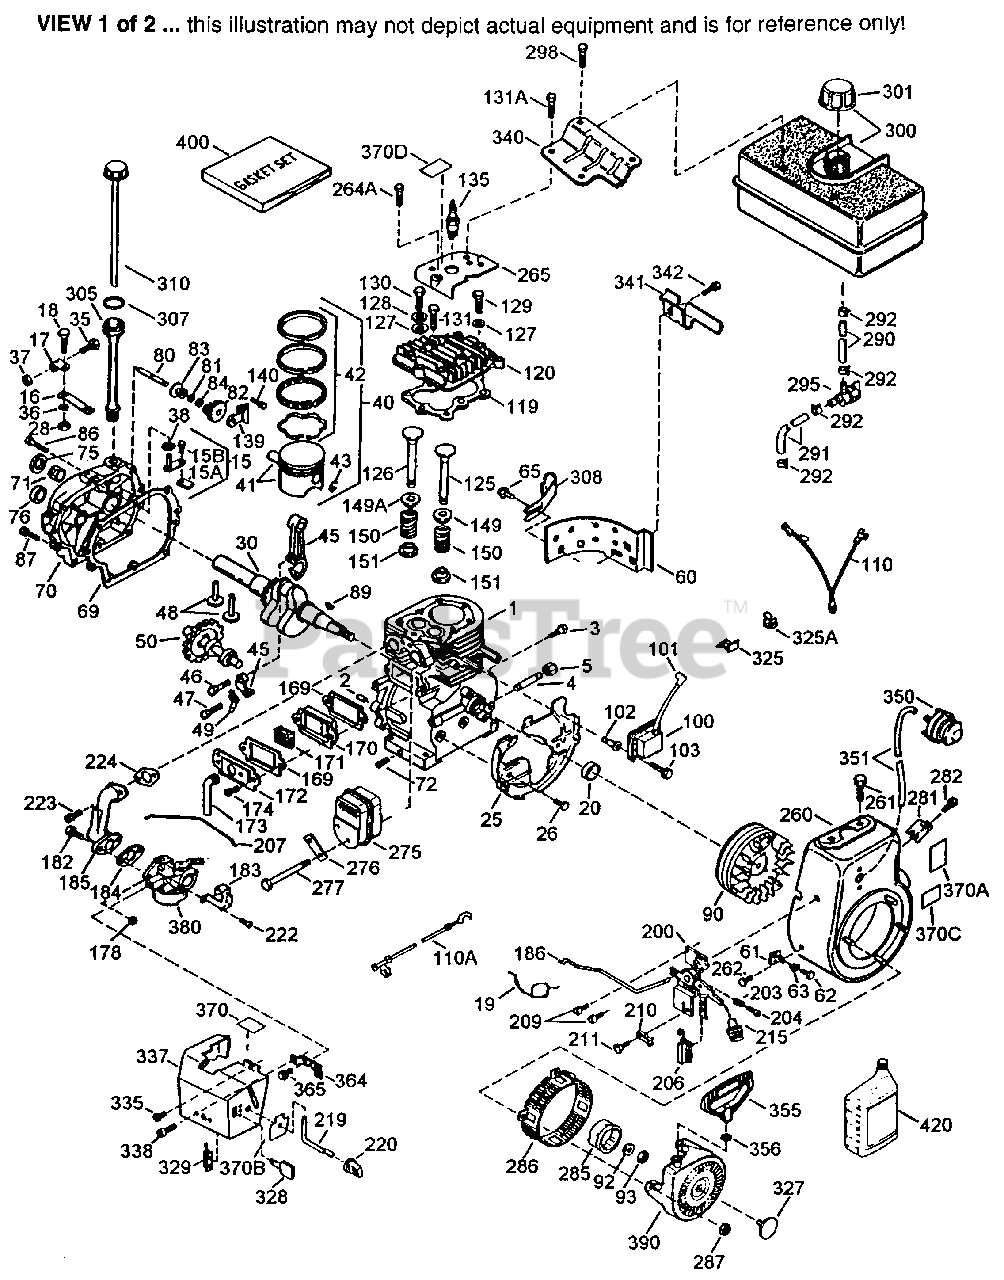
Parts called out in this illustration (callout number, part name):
1	"Cylinder Ass'y. (Incl. 2, 20, 72 & 72 A)(3-1/8" Bore)
2	Dowel Pin
3	Screw, 1/4-20 x 1/2"
4	Oil Drain Extension Purchase Locally
5	Extension Cap
15	Governor Rod (Incl. 15A & 15B)
15A	Governor Yoke
15B	Screw, 6-40 x 5/16"
16	Governor Lever
17	Governor Lever Clamp
18	Screw, 8-32 x 5/16"
19	Speed Control Spring
20	Oil Seal
25	Blower Housing Baffle
26	Screw, 1/4-20 x 5/8"
28	Lock Nut, 8-32
30	Crankshaft
35	Screw, 10-32 x 3/4"
36	Lock Washer #8
37	Lock Nut, 10-32
38	Retaining Ring
40	Piston, Pin & Ring Set (Std.)
40	Piston, Pin & Ring Set (.010" OS)
40	Piston, Pin & Ring Set (.020" OS)
41	Piston & Pin Ass'y. (Std.) (Incl. 43)
41	Piston & Pin Ass'y. (.010" OS) Incl. 43
41	Piston & Pin Ass'y. (.020" OS) Incl. 43
42	Ring Set (Std.)
42	Ring Set (.010" OS)
42	Ring Set (.020" OS)
43	Piston Pin Retaining Ring
45	Connecting Rod Ass'y. (Incl.46,47,49)
46	Connecting Rod Bolt
47	Connecting Rod Bolt
48	Valve Lifter
49	Oil Dipper
50	Camshaft (MCR)
60	Blower Housing Extension
61	Grommet Mounting Bracket
62	Screw, 8-32 x 3/8"
63	Breather Tube Grommet
65	Screw, 10-24 x 1/2"
69	* Cylinder Cover Gasket
70	Cylinder Cover (Incl. 71, 75 & 80)
71	Crankshaft Bushing
75	Oil Seal
76	Camshaft Seal
80	Governor Shaft
82	Governor Gear Ass'y. (Incl. 81)
83	Governor Spool
84	Retaining Ring
86	Screw, 1/4-20 x 1-3/16"
87	Screw, 1/4-20 x 1-11/16"
89	Flywheel Key
90	Flywheel (W/Ring Gear)
92	Lock Washer
93	Flywheel Nut
100	Solid State Ignition
101	Spark Plug Cover
102	Solid State Mounting Stud
103	Screw, Torx T-15, 10-24 x 15/16"
110	Ground Wire (One male, One female, On e eyelet)
110A	Ground Wire (One male, One open eyele t)
119	* Cylinder Head Gasket
120	Cylinder Head
125	Exhaust Valve (Std.)(Incl. 151)
125	Exhaust Valve (1/32" OS) (Incl. 151)
126	Intake Valve (Std.) (Incl. 151)
126	Intake Valve (1/32" OS) (Incl.151)
129	Screw, 5/16-18 x 1-3/4"
130	Screw, 5/16-18 x 1-1/2"
131A	Screw, 5/16-18 x 5/8"
135	Resistor Spark Plug - RJ17LM
139	Governor Gear Bracket
140	Screw, 10-24 x 1/2"
149	Valve Spring Cap
149A	Valve Spring Cap
150	Valve Spring
151	Valve Spring Keeper
169	* Valve Cover Gasket
170	Breather Body
171	Breather Element
172	Valve Cover
173	Breather Tube
174	Screw, 10-24 x 1/2"
178	Nut & Lock Washer 1/4-28
182	Screw, 1/4-28 x 1"
183	Choke Bracket
184	* Carburetor To Intake Pipe Gasket
185	Intake Pipe
186	Governor Link
186B	Choke Spring
200	Control Bracket Incl. 19, 203, 204 & 206
203	Compression Spring
204	Screw, 5-40 x 7/16"
206	Terminal
207	Throttle Link
209	Screw, 10-32 x 1/2"
215	Control Knob
219	Choke Rod
220	Control Knob
222	Screw, 10-32 x 1/2"
223	Screw, Torx T-30, 5/16-18 x 1-1/8"
224	* Intake Pipe Gasket
260	Blower Housing
261	Screw, 5/16-18 x 3/4"
262	Screw, T-40, 5/16-24 x 21/32"
264A	Screw, 1/4-20 x 5/8"
265	Cylinder Head Cover
275	Muffler
276	Locking Plate
277	Screw, 5/16-18 x 4-3/16"
281	Starter Bubble Cover
282	Screw, 8-32 x 3/8"
285	Starter Cup
287	Nut & Lock Washer 1/4-28
290	Fuel Line (8.62")
291	Fuel Line
292	Fuel Line Clamp
295	Fuel Shut-Off Valve (Incl. 292) also available in Packaged Part #740073
298	Screw, 1/4-15 x 7/8"
300	Fuel Tank (Incl. 292 & 301)
301	Fuel Cap (Red)
305	Oil Fill Tube
307	"O" Ring
308	Fill Tube Clip
310	Dipstick
325	Wire Clip
327	Starter Plug
328	Ignition Key
329	Terminal
335	Carburetor Cover
336	Screw, 10-32 x 1/2"
338	Screw, 10-32 x 3/8"
340	Fuel Tank Bracket
341	Fuel Tank Bracket
342	Screw, 1/4-20 x 5/8"
350	Primer Ass'y.
351	Primer Line
355	Starter Handle (Mitten Grip) also ava ilable in Packaged Part #740053B
364	Carburetor Cover Bracket
365	Screw, 8-32 x 27/64"
370	Decal - Speed Control & Choke
370A	Primer Decal
370B	Instruction Decal
370C	Warning Decal
380	Carburetor (Incl. 184)
390	Rewind Starter
396	Electric Starter Motor (Optional)
400	* Gasket Set (Incl. items marked PK in notes) Incl. part #'s 27272A (1),278 96A (2), 27915A (1), 29673 (1), 33263 (1), 33629 (1), 34698A (1), 35262A ( 1), 36448 (1)
